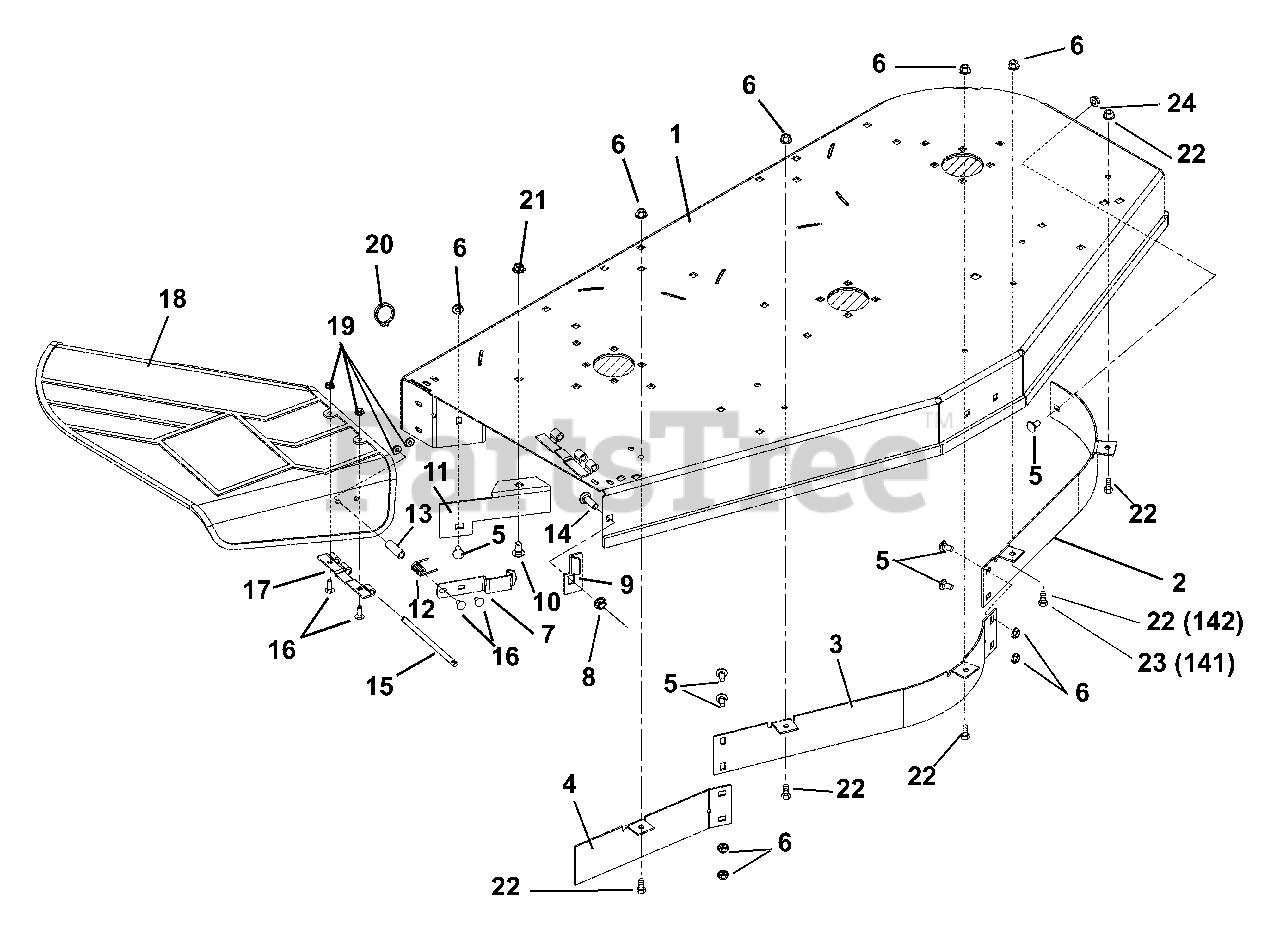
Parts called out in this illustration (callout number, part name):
1	WMT, DECK 48" CONSUMER CZ
1	WMT, DECK 44" CONSUMER CZ
2	BAFFLE - LEFT FRONT - 48"
2	BAFFLE - LEFT FRONT - 44"
3	BAFFLE - CENTER FRONT - 48"
3	BAFFLE - CENTER FRONT - 44"
4	BAFFLE - RIGHT FRONT - 48"
4	BAFFLE - RIGHT FRONT - 44"
5	@BLT-RHDSSQNK .31-18X.62 G5YZ
6	@NUT-LK-NYL-FLG .31-18 YWZC
7	FLAT SPRING
8	@NUT-LK-TOP-FLG .38-16 YWZC
9	BRACKET, CHUTE LOCK
10	@BLT-RDHDSQNK .38-16X.75 G5YZ
11	DEFLECTOR-44"/48"
12	SG-TORS .095X.50X 1.0
13	BSHG-SLV .334 X .502 X 1.437
14	@BLT-RDHDSQNK .38-16X1.25 G5YZ
16	@BLT-RDHDSQNK .25-20X.75 G5YZ
17	HINGE PLATE
18	DEFLECTOR, CHUTE
19	@NUT-LK-NYL-FLG .25-20 YWZC
20	RG-RTNG-EXT .312X.025
21	@NUT-LK-NYL-FLG .38-16 YWZC
22	@BLT-HEX .31-18X.75 GR5 YWZC
23	@BLT-HEX .31-18X1.00 GR5 YWZC
24	@NUT-LK-CTR-JAM .31-18 YWZC
